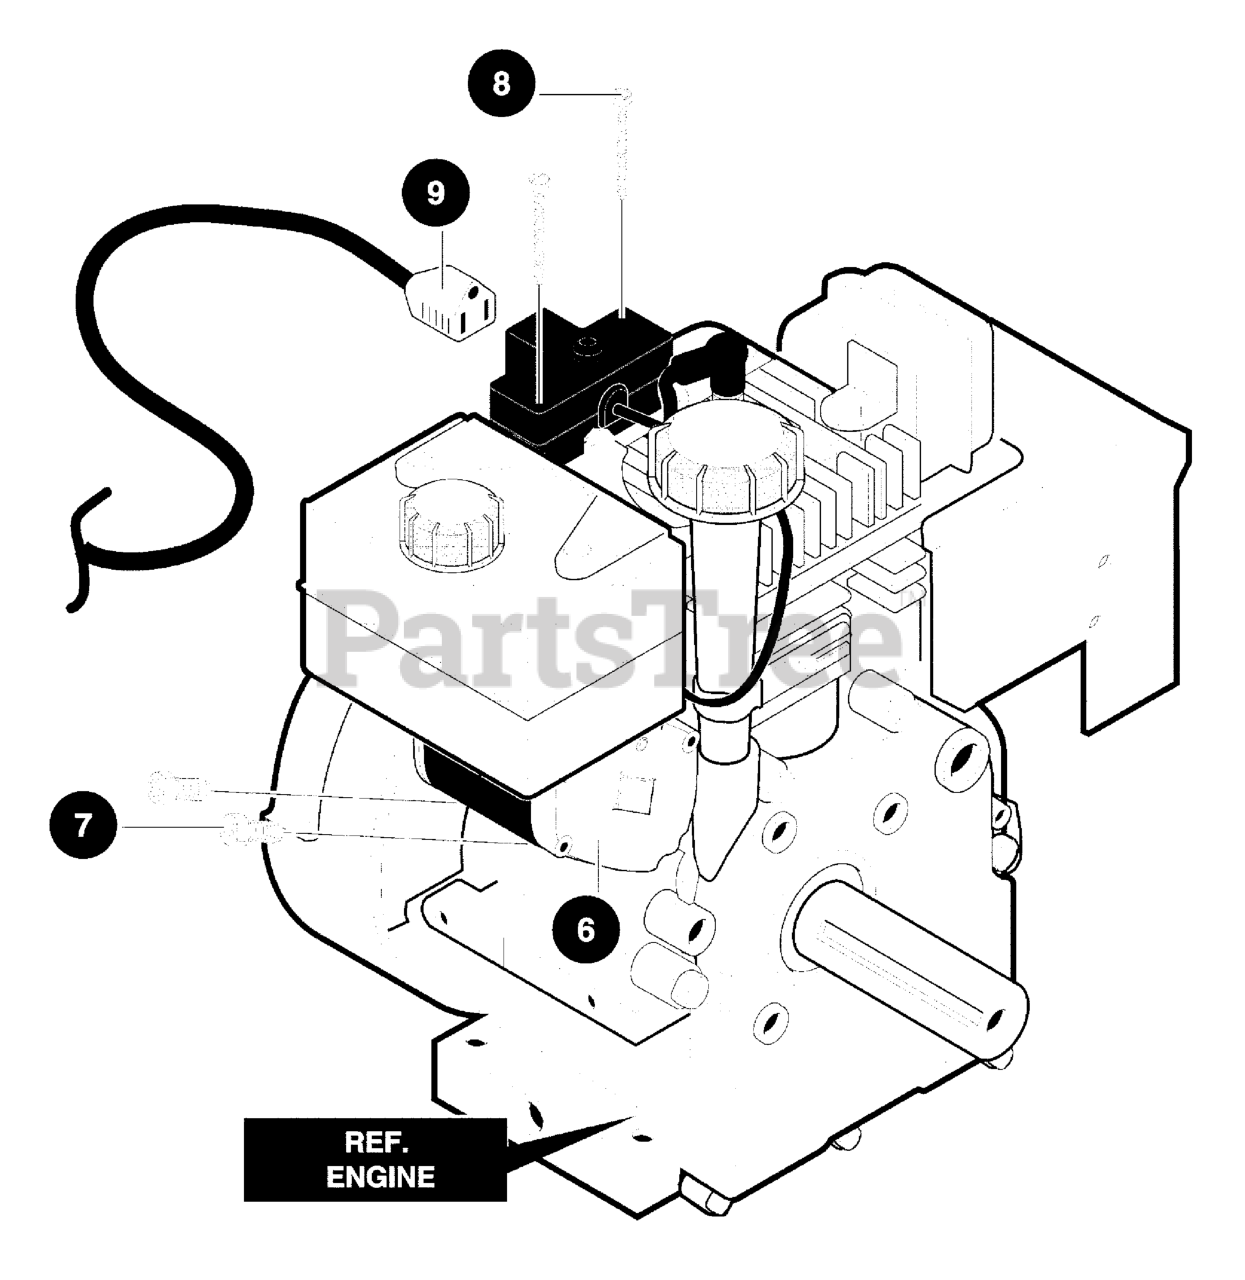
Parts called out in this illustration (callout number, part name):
6	MOTOR, STARTER
7	SCREW, 1/4-20X.50
8	SCREW, #6-32X2.50
9	CORD, Electric, 10FT. 110V
